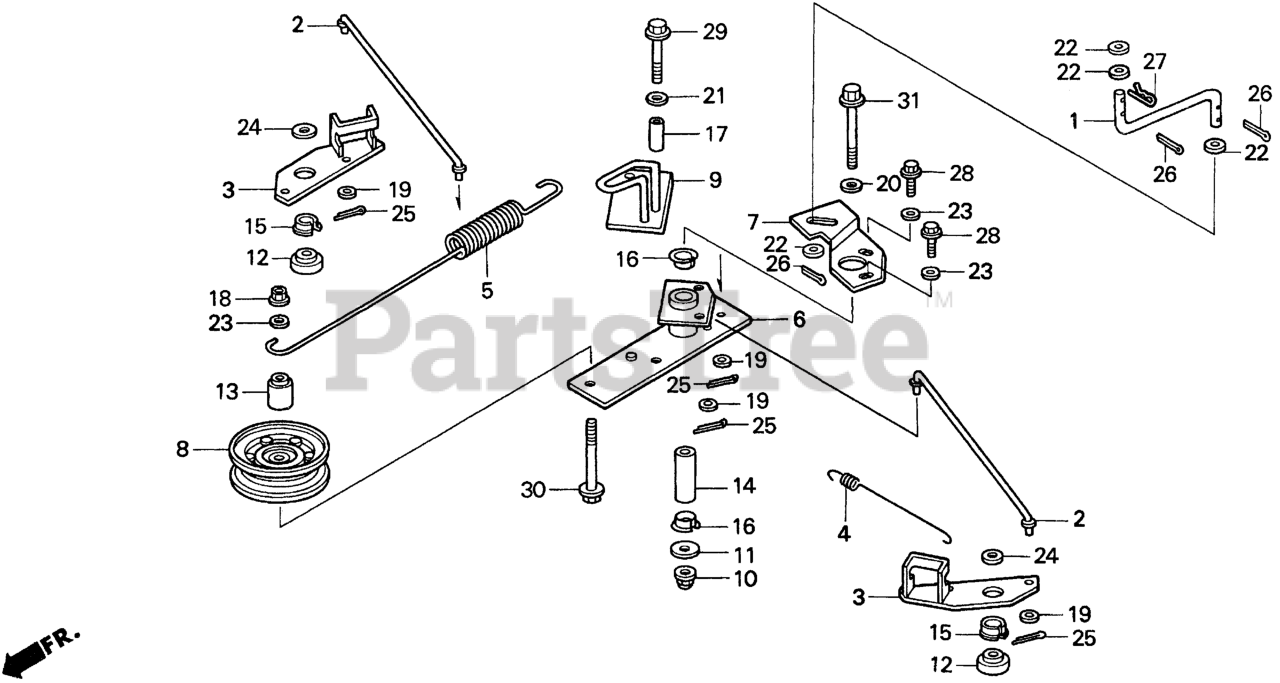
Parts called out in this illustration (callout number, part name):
1	ROD, P.T.O. CLUTCH
2	ROD, BLADE BRAKE
3	ARM, BLADE BRAKE
4	SPRING, BLADE BRAKE
5	SPRING, TENSIONER ARM
6	ARM, TENSIONER
7	PLATE, ADJUSTING
8	ROLLER, TENSIONER
9	STOPPER D, BELT
10	NUT, SELF-LOCK (10MM)
11	WASHER, PLAIN (10MM)
12	COLLAR, BLADE BRAKE
13	COLLAR, TENSIONER SPRING
14	COLLAR, TENSION
15	COLLAR B, BLADE BRAKE
16	COLLAR C, TENSIONER
17	COLLAR A, ADJUSTING CENTER
18	NUT, FLANGE (8MM)
19	WASHER, PLAIN (6MM)
20	WASHER, PLAIN (10MM)
21	WASHER, PLAIN (8MM)
22	WASHER, PLAIN (10MM)
23	WASHER, PLAIN (8MM)
24	WASHER, PLAIN (10MM)
25	PIN, COTTER (2.5MM) (SOURCE: VINTAGE PARTS INC.)
26	PIN, SPLIT (3.0X25)
26	PIN, COTTER (3.0X45)
27	PIN, LOCK (10MM) Use from Frame SN 2149606 to 2149605.
28	BOLT, FLANGE (8X20)
29	BOLT, FLANGE (8X50)
30	BOLT, FLANGE (8X75)
31	BOLT, FLANGE (10X80)
